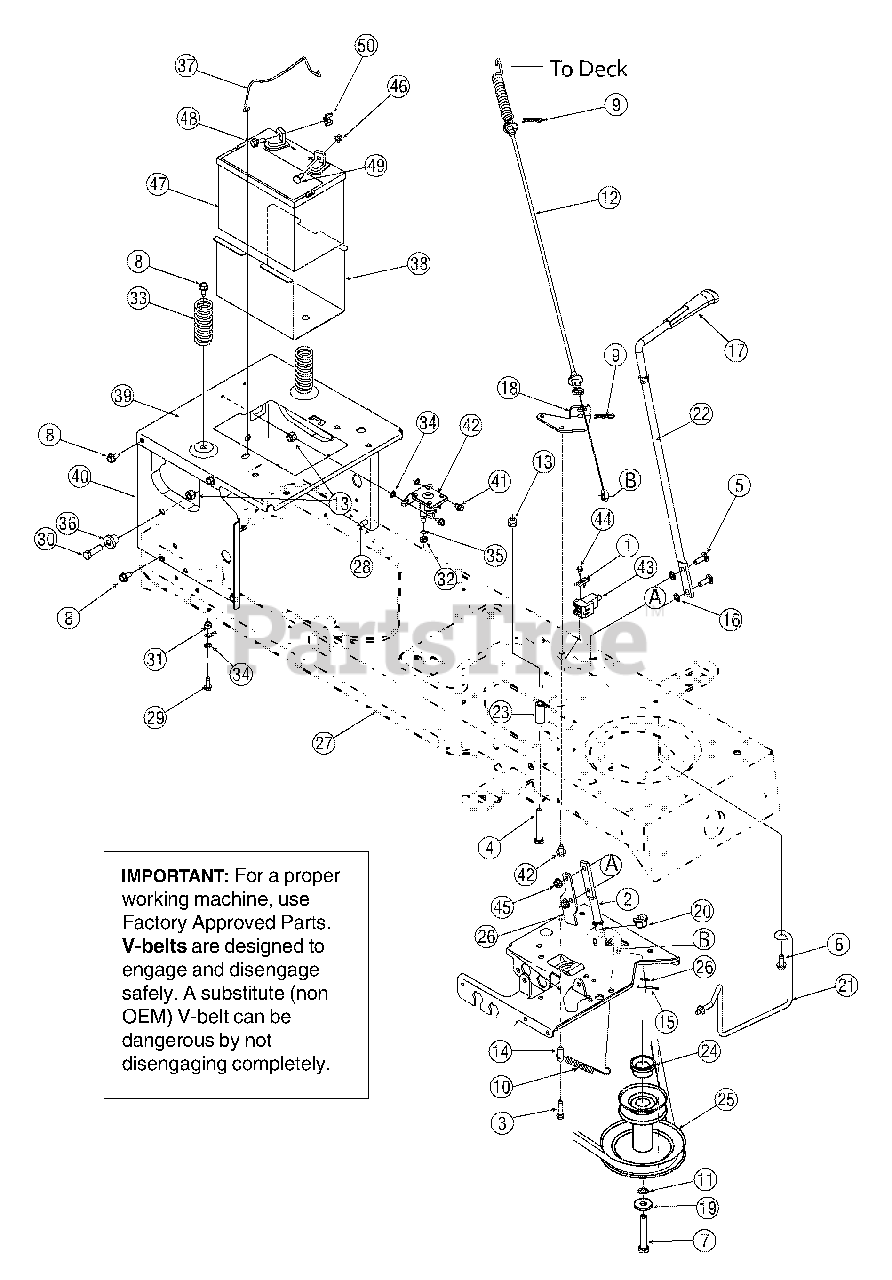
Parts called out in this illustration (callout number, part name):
1	Plate, Switch
2	Lever Assembly, Engagement
3	Screw, 1/4-20 x 1.250
4	Screw, 3/8-16, 2.50
5	Screw, Carriage, 5/16-18, 1.00
6	Screw, 5/16-18 x.750
7	Screw, 7/16-20, 3.25, Gr5
8	Screw, 5/16-12, 0.750
9	Click Pin
10	Extension Spring,.38OD x 3.9LG
11	Lock Washer, 7/16
12	Deck Engagement Cable
13	Nut, Flange Lock, 3/8-16, Gr F, Nylon
14	Spacer,.260 x.372 x 1.030LG
15	Pin, Cotter, 1/8 x 1.25
16	Nut, Speed,.3125 ID
17	Knob, PTO
20	Bearing, Flange, Hex Split.500 ID
21	Keeper Rod, Belt
23	Spacer,.385 ID x.635 OD x 1.54
24	Spacer, 1.010 x 1.400 x.825
25	Pulley, Engine, 3.39 x 6.12 Diameter
29	Screw, 1/4-20, 0.750
30	Screw, 3/8-16, 1.25, Gr5
31	Nut, Flange Lock, 1/4-20, Gr F, Nylon
32	Nut, Hex, 1/4-20, Gr5
33	Spring, Compression, 1.28 OD x 3.125
34	Washer, Lock, 1/4, External
35	Washer, Lock, 1/4
36	Spacer, Shoulder,.38 x 1.0 x.70
37	Hold Rod, Battery
41	Screw, 1/4-20, 0.50
42	Solenoid, 12V, 100 Amp
43	Switch, Interlock
44	Screw, #10-16,.50
45	Nut, Flange, Lock Nut, 5/16-18
46	Nut, Sems, 1/4-20
47	Battery, 190 CCA
48	Screw, Shoulder,.250 x.15, 1/4-20
49	Screw, Carriage, 1/4-20,.75
50	Nut, Wing, 1/4-20
